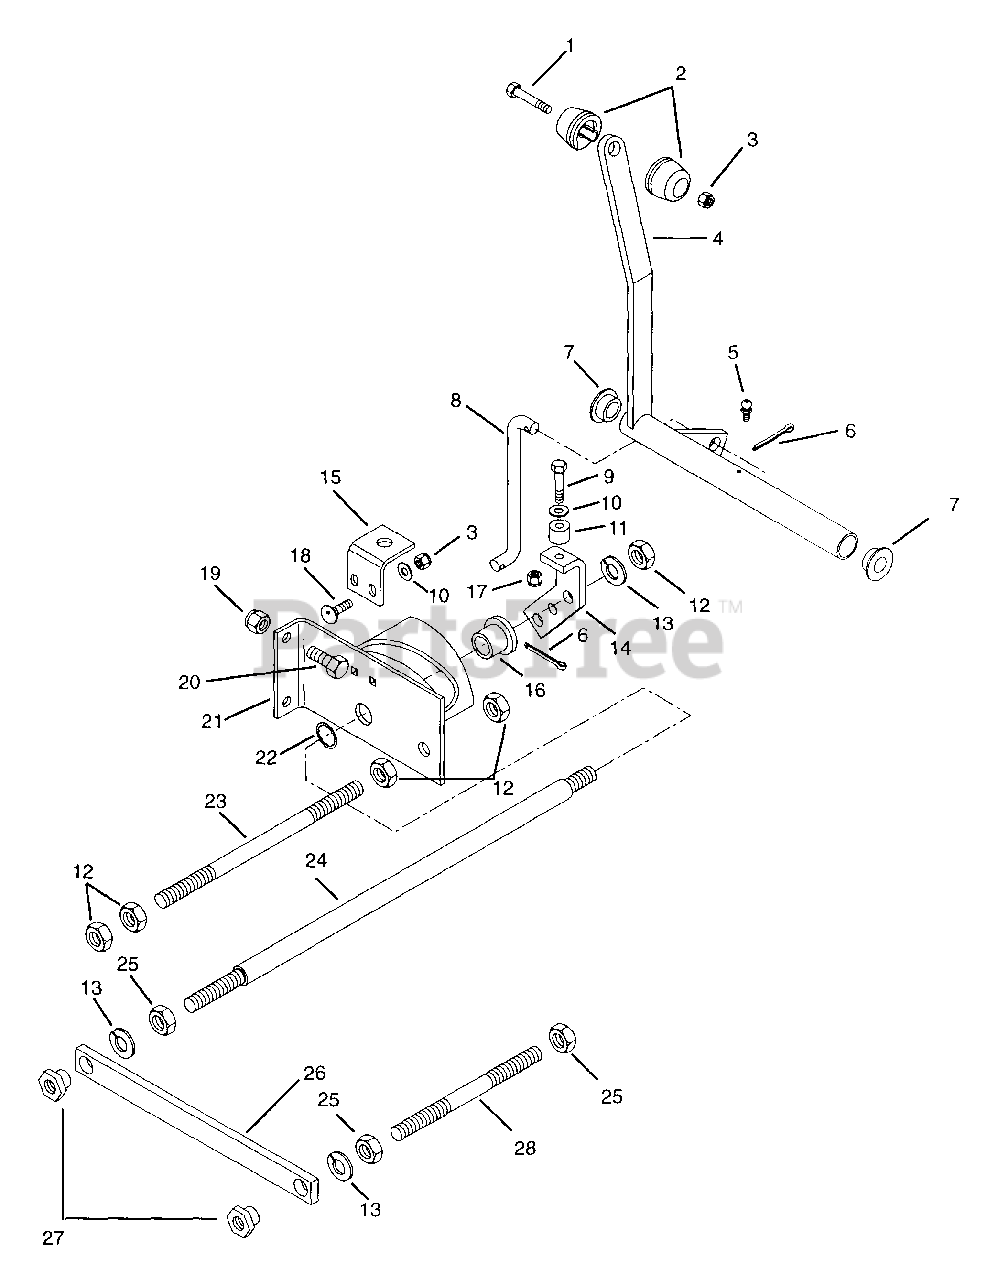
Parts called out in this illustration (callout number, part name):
1	Bolt-Hex .25-20 x 1.50
2	Knob, Control
3	Nut-Locking-Nylon .250-20 Grade 2
4	Control, PTO
5	Fitting-Lube .25-28 x .256
6	Pin-Cotter .09 x 1.0
7	Bushing-Flange .515 x .750 x .745 x 1.00
8	Rod, PTO
9	Bolt-Hex .25-28 x 1.38
10	Washer-Flat-Steel .281 x .625 x .065
11	Roller-Clutch Cam .250 x .750 x .5625
12	Nut .50-13
13	Washer-Lock .500 x .151
14	Arm, PTO Clutch Roller
15	Bracket, Interlock
16	Bearing-Flange 2.00
17	Nut-Locking-Nylon .250-28 Grade 2
18	Bolt-Round Head Square Neck .25-20 x .75
19	Nut-Locking-Nylon .375-16 Grade 2
20	Bolt-Hex .38-16 x 1.00 Grade 5
21	Weldment, PTO Bracket
22	Ring-Retaining-External 1.31 x .05
23	Rod, Lift
24	Rod, PTO
25	Nut-Jam .50-13 Grade 2
26	Spring, PTO
27	Bushing-Flange .500 x .875 x .700
28	Stud, PTO
